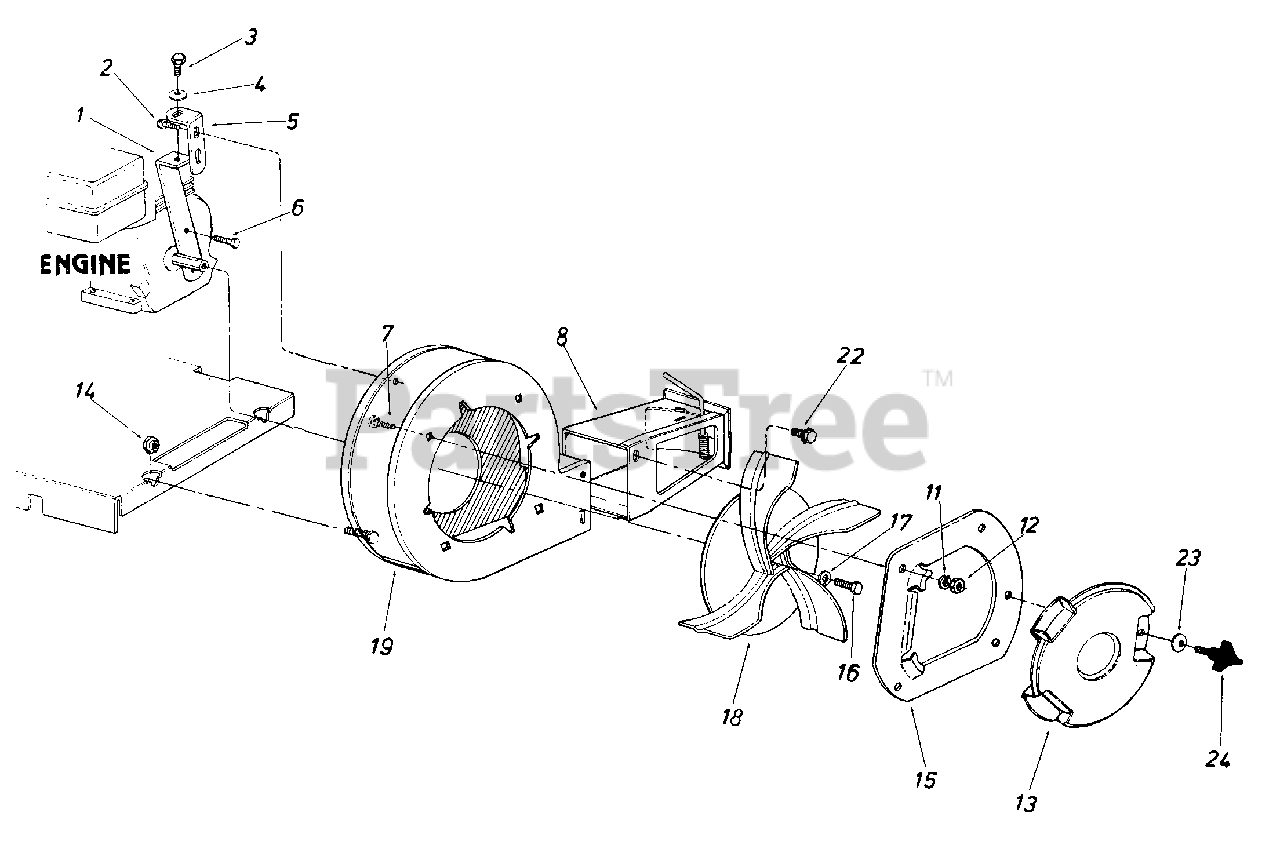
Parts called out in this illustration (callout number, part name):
3	Hex Bolt 5/16-18 x .75" Lg.*
4	L.-Wash.5/16" I.D.*
7	Carriage Bolt 5/16-18 x .62" Lg. *
12	Hex Nut 5/16-18 Thd.*
13	Blower Guard
14	Hex Shoulder Nut .50" I.D.
15	Nozzle Plate Ass'y.
16	Hex Bolt 3/8-24 x 1.25" Lg.*
17	L.-Wash. 3/8" I.D. HD.
18	Air Vane Plate Ass'y.
19	Blower Housing Ass'y. - Comp.
22	Hex Sems Bolt 5/16-18 x .62" Lg.*
23	BellevilleWash.34" I.D. x .87" O.D.
24	3-Arm Thumb Scr. 5/16-18 x .75" Lg.
